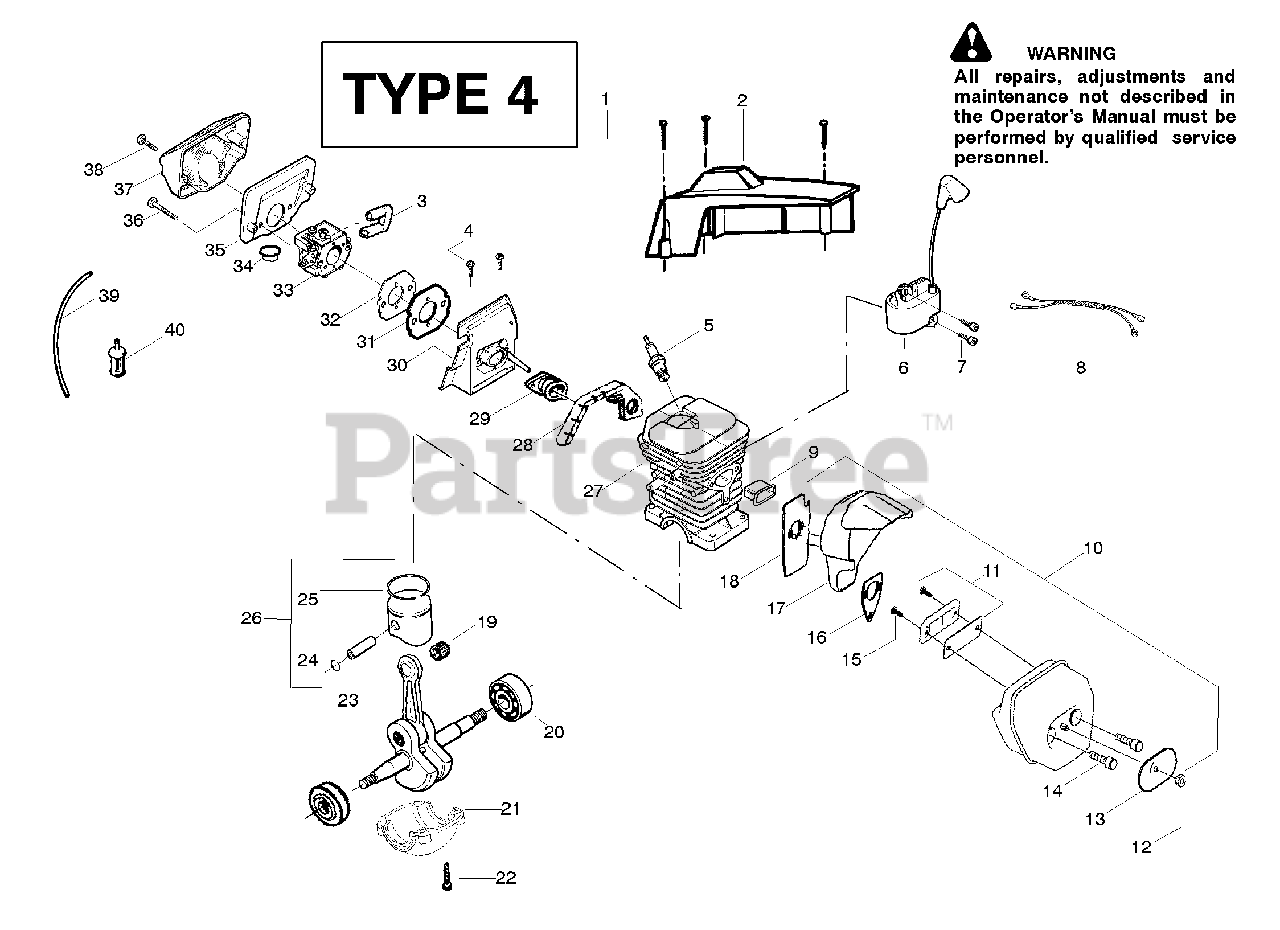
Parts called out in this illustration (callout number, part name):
2	Kit-Cylinder Shield
3	Grommet -Carb.
5	Spark Plug
6	Module-Ignition
8	Assy-Switch Wire
9	Insulator-Heat
10	Kit-Muffler
11	Kit-Spark Arrestor
12	Nut-Brass
13	Cover-Bolt
14	Bolt-Muffler
15	Screw-Spark Screen
16	Gasket-Muffler
17	Assy-Muffler Backplate
18	Backplate - Alum.
19	Bearing-Piston Pin
20	Assy-Bearing & Seal
21	Cap-Crankcase
23	Assy-C'shaft & Rod
24	Retainer-Piston Pin
25	Ring-Piston
26	Kit-Piston
27	Assy-Cyl/Crankcase
28	Seal-Super Clean
29	Intake Boot
30	Adapter-Carb.
31	Intake Plate-Carb
32	Gasket-Carb.
33	Kit-Carburetor
34	Isolator
35	Filter-Air
37	Filter-Air
39	Kit-Fuel Line
40	Assy-Fuel Pick-up
